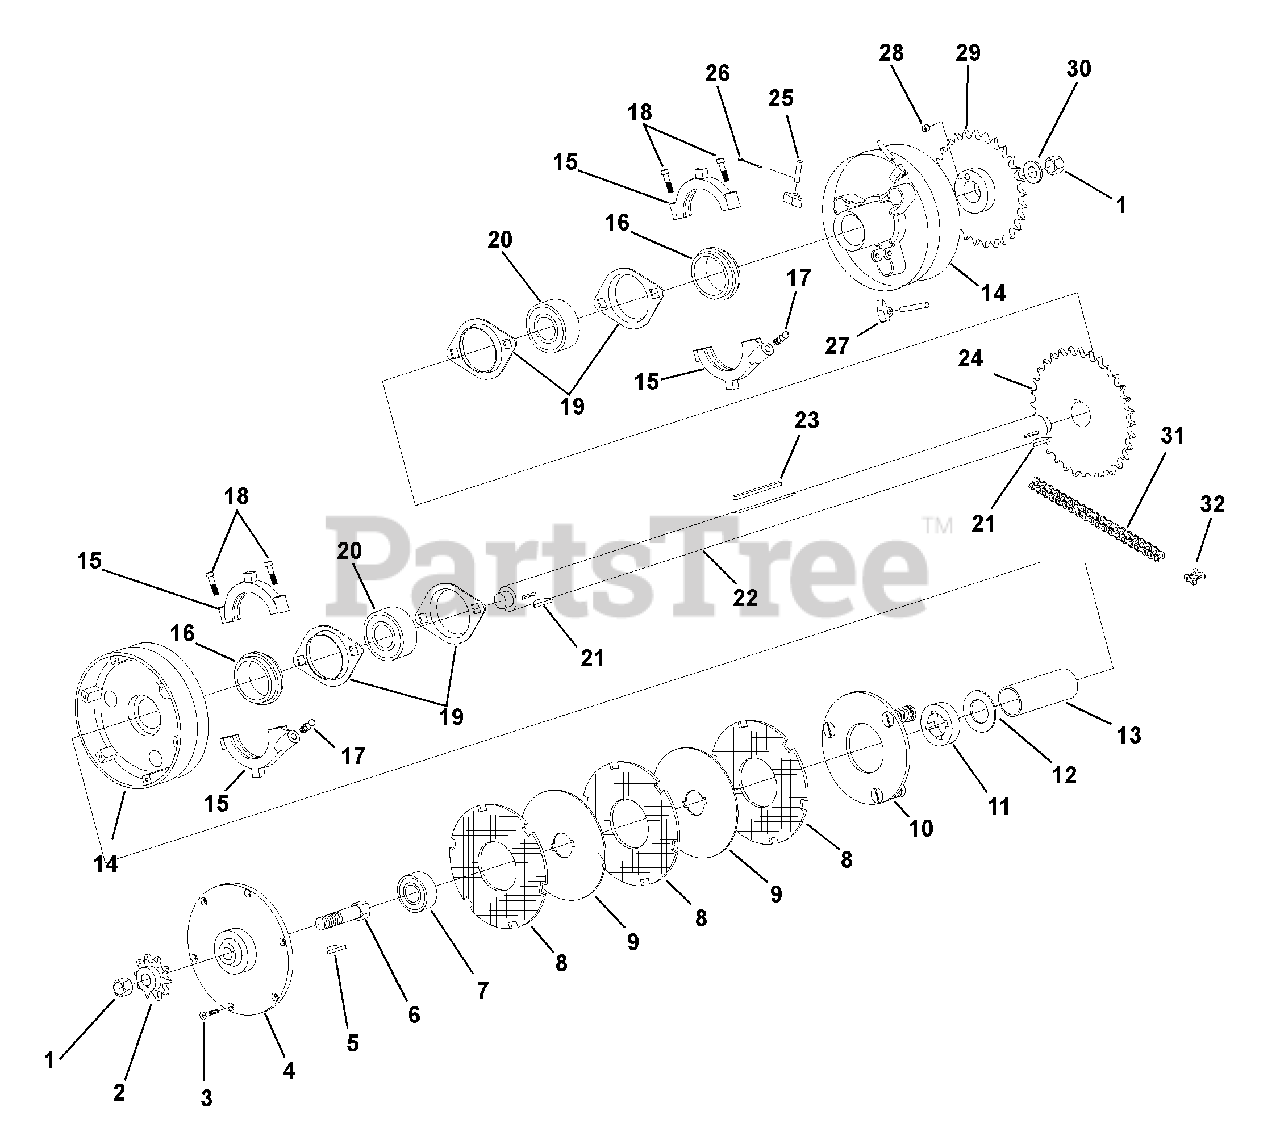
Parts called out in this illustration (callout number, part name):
1	Nut, Hex .50-20
2	Sprocket, 10 Tooth
3	Screw, Flat Head Machine 10-32 x .625 Stainless Steel
4	Cover, Clutch
5	Key, Woodruff .187 x .75
6	Stud, Sprocket
8	Disc, Clutch
9	Plate, Clutch
10	Plate, Pressure #40
11	Retainer, Key
12	Washer, Thrust
13	Bushing, Sintered Iron Copper
14	Assembly, Clutch Housing (Includes Item # 13)
15	Collar, Bronze
16	Cone, Clutch
17	Fitting, Grease .25-28
18	Screw, Phillips Round Head Machine 10-32 x 1
19	Flange, Bearing
21	Key, Woodruff .25 x .875
22	Shaft, Clutch 25-Inch (995030, 032)
23	Key .25 x 2.375
24	Sprocket, 32-Tooth
25	Sprocket, 40B20 x 1-Inch 028690006Pin, Clevis .187 x 1
26	Pin, Cotter .062 x .50
27	Clutch Dog
28	Key, Clutch (Brass Bushing Used as Shear Pin)
29	Sprocket, 28-Tooth
30	Washer, Flat
31	Chain, Clutch Shaft (Kohler 31.5" #423)
32	Master Link #423
